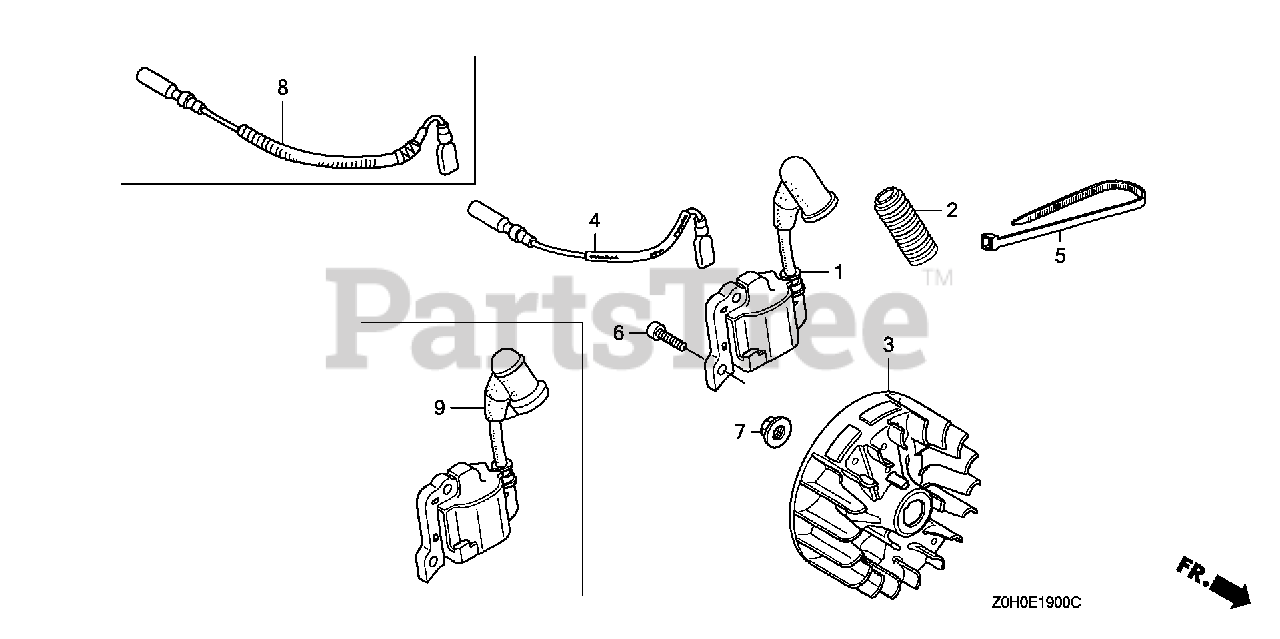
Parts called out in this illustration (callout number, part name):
1	COIL ASSY., IGNITION
2	TUBE, CORRUGATE
3	FLYWHEEL
4	WIRE, STOP SWITCH
5	TIE, CABLE
6	BOLT, SOCKET (4X14)
7	NUT, FLANGE (7MM)
9	COIL ASSY., IGNITION
